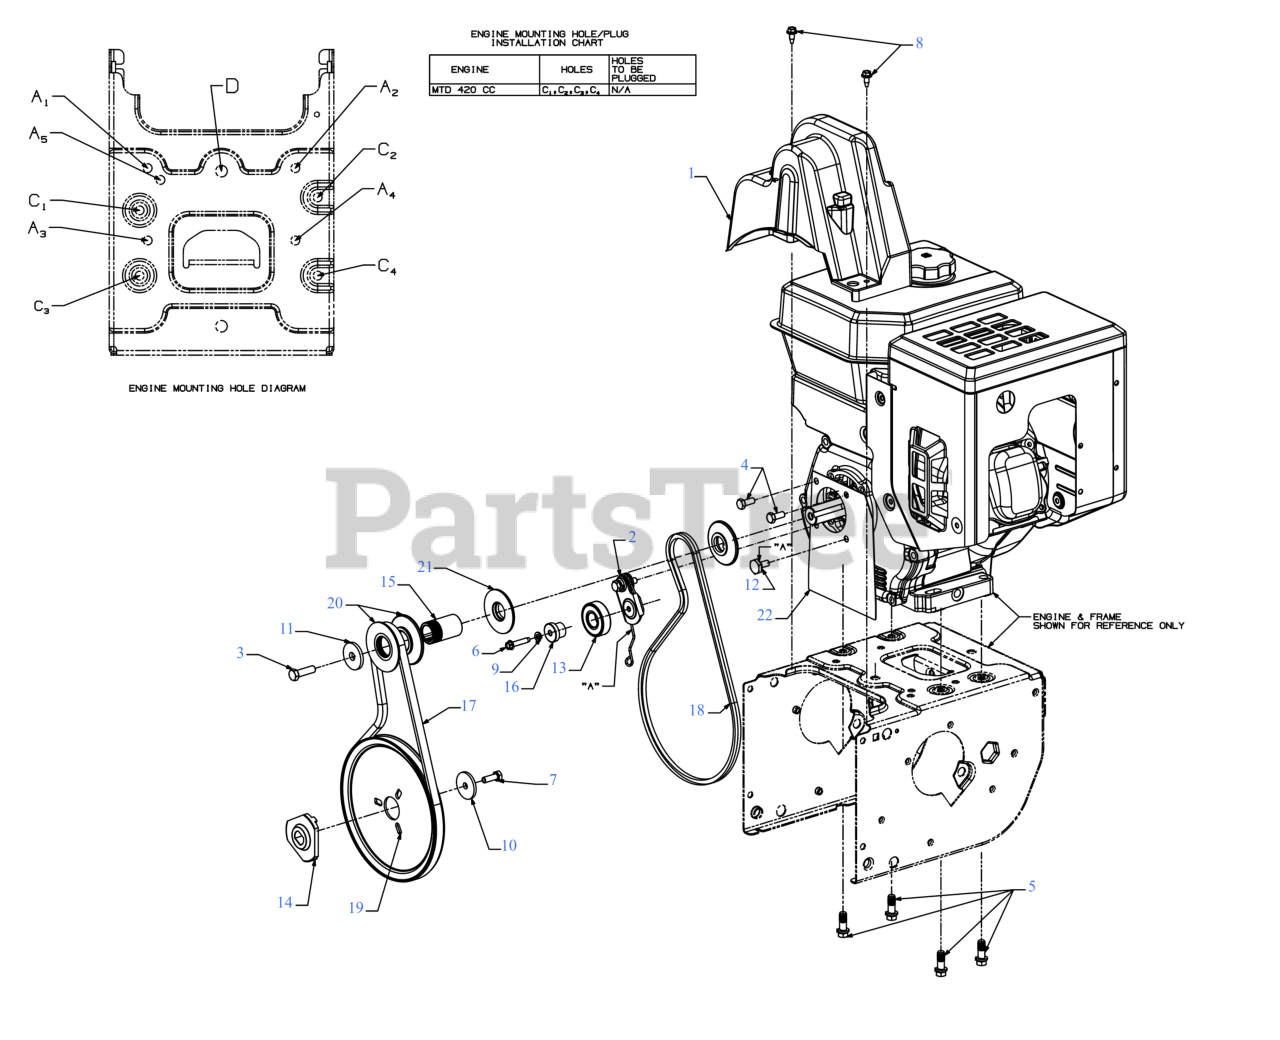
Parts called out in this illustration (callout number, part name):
1	BELT COVER (LARGE BLOCK)
3	SCREW 3/8-24X1.25
4	SCREW 5/16-24 x .750 GR5
5	SCREW 3/8-16 x 1
6	SCREW 1/4-20 x 1.25
7	SCREW 5/16-24 x .875 GR5
8	SCREW 1/4-20X.625
9	LOCK WASHER
10	FLAT WASHER
11	FLAT WASHER .45 x 1.5 x .172 HT
12	SHOULDER SCREW
13	BALL BEARING
14	ADAPTER PULLEY .75 DIA W/DD
15	PULLEY SPACER
16	SHOULDER SPACER
17	BELT-.500 x 37.00
18	BELT-3L x 36.64 LG
19	AUGER PULLEY
20	HALF PULLEY 4L V x 2.6 OD
21	HALF PULLEY 3/8-V x 2.2
22	ENGINE PLATE (FRONT COVER)
